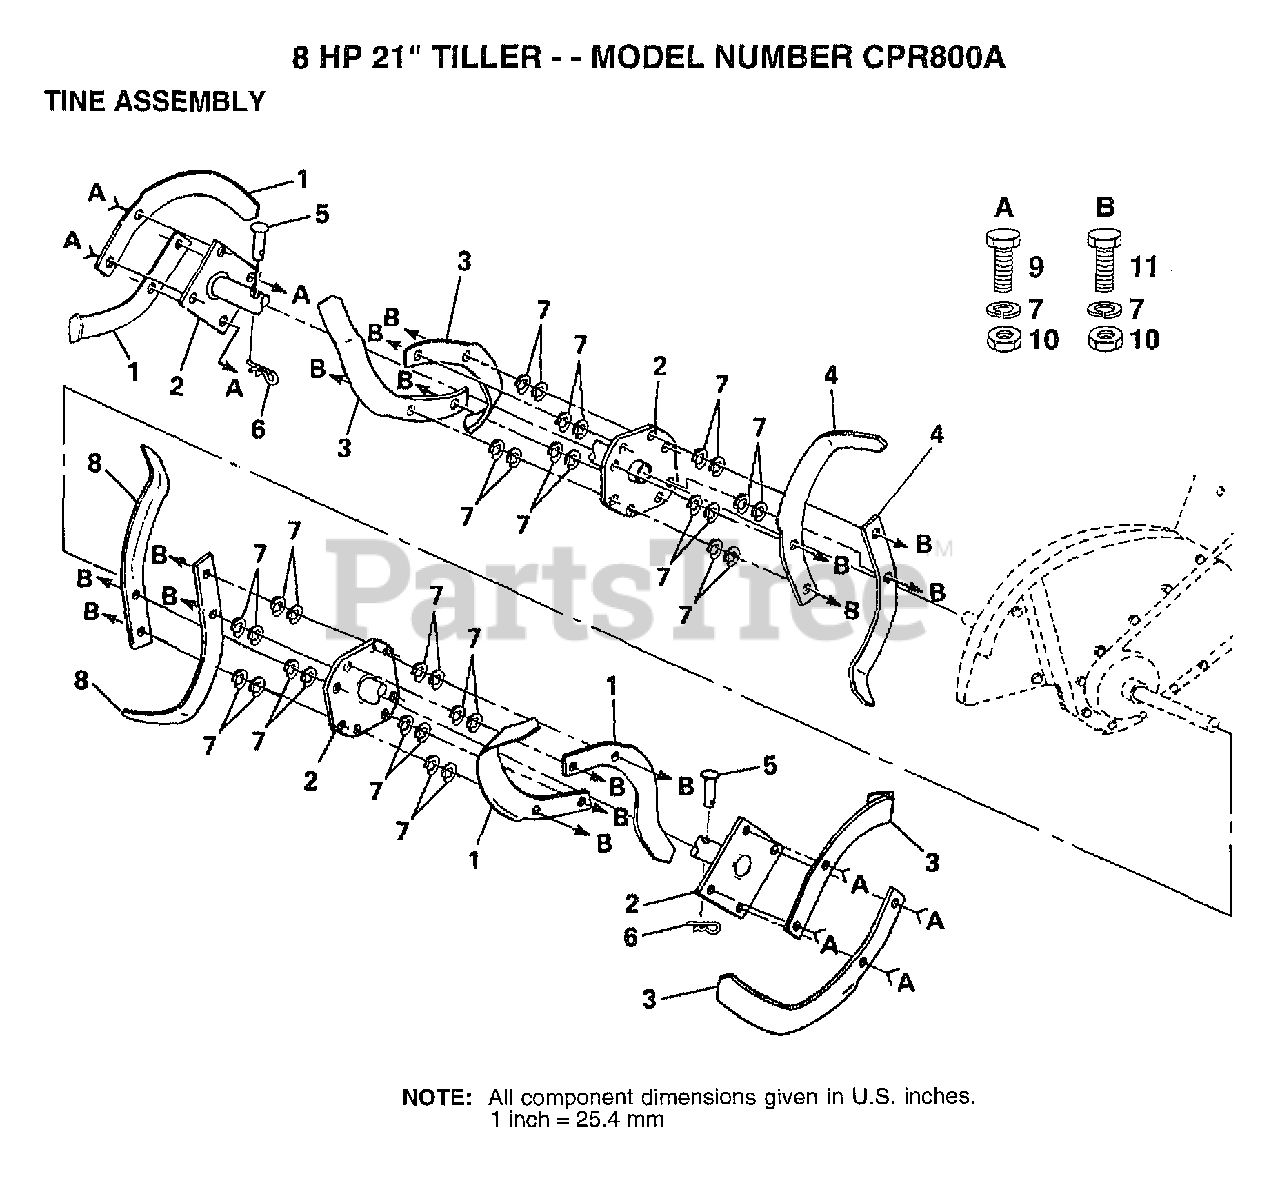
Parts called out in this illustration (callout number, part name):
2	TINE ASSY CRT
4	TINE.LH.CRT
5	RIVET.PAN HD.1.75
6	RETAINER.SPRING
7	LOCKWASHER
8	TINE RH CRT
9	BOLT
11	BOLT.3/8-24X1-1/2
